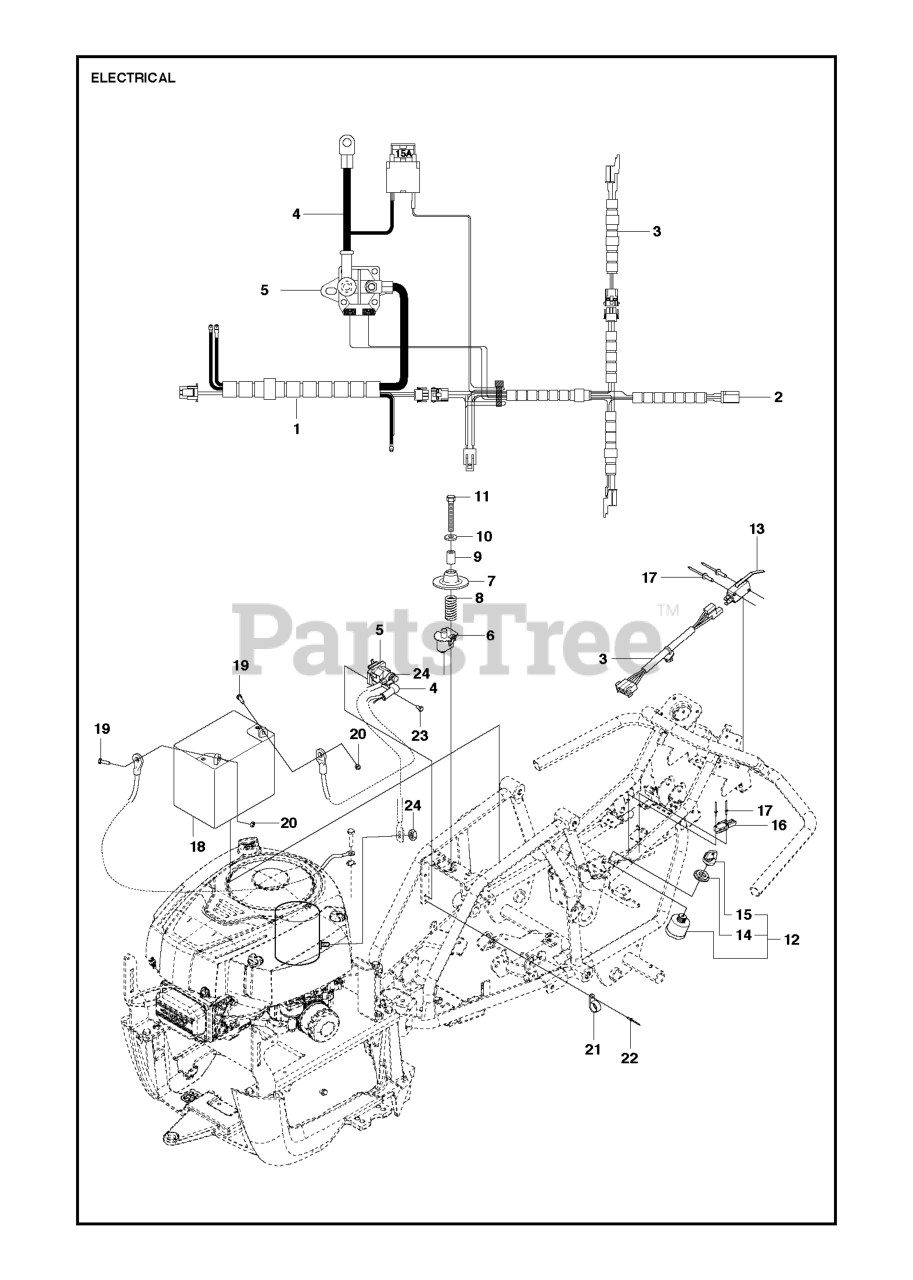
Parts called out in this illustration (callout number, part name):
1	WIRING
9	SPACER TUBE
10	WASHER BRB 8.4X17
11	SCREW
12	IGNITION SWITCH
15	IGNITION KEY
16	MICRO SWITCH
19	SCREW EHHM
21	CABLE CLAMP
